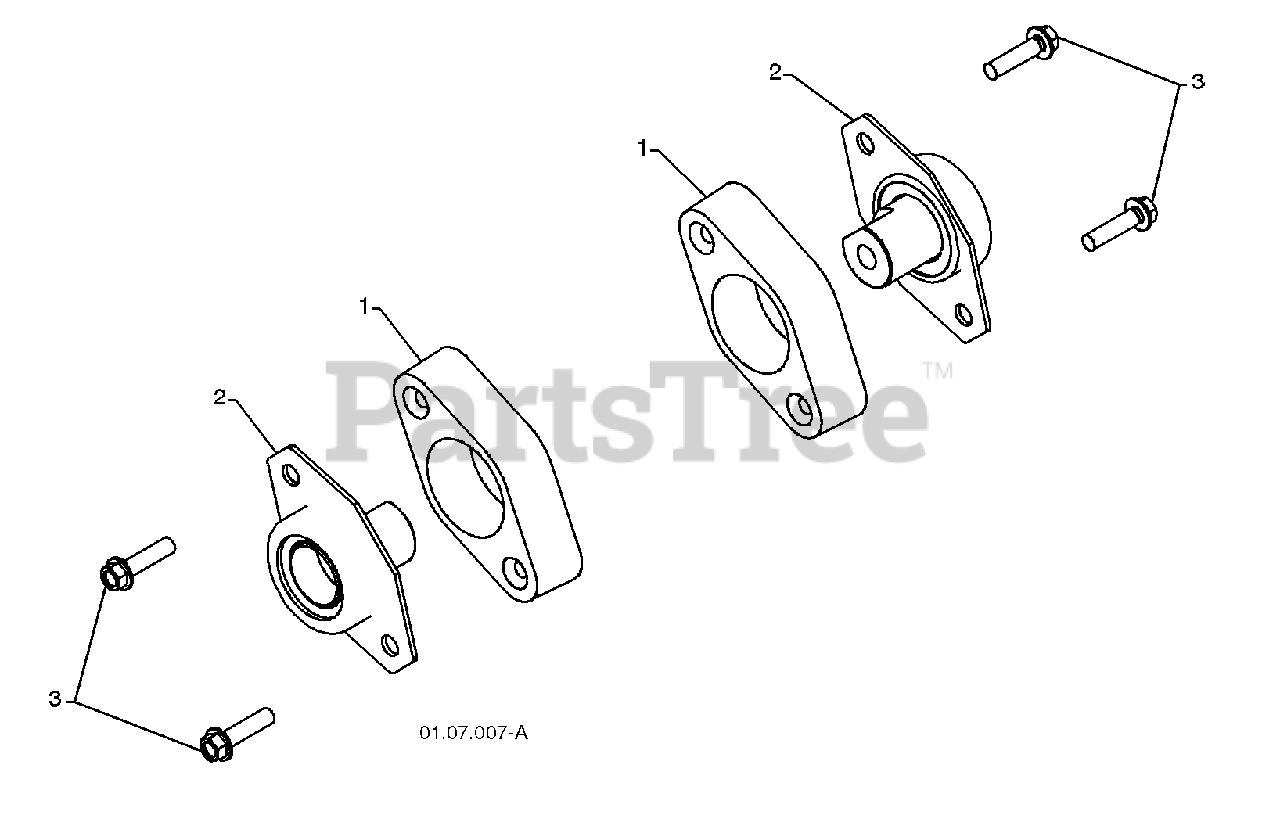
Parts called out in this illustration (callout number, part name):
1	PLASTIC RETAINER
2	AUGER BALL BEARING
3	SCREW 5/16-18 X 1.00
